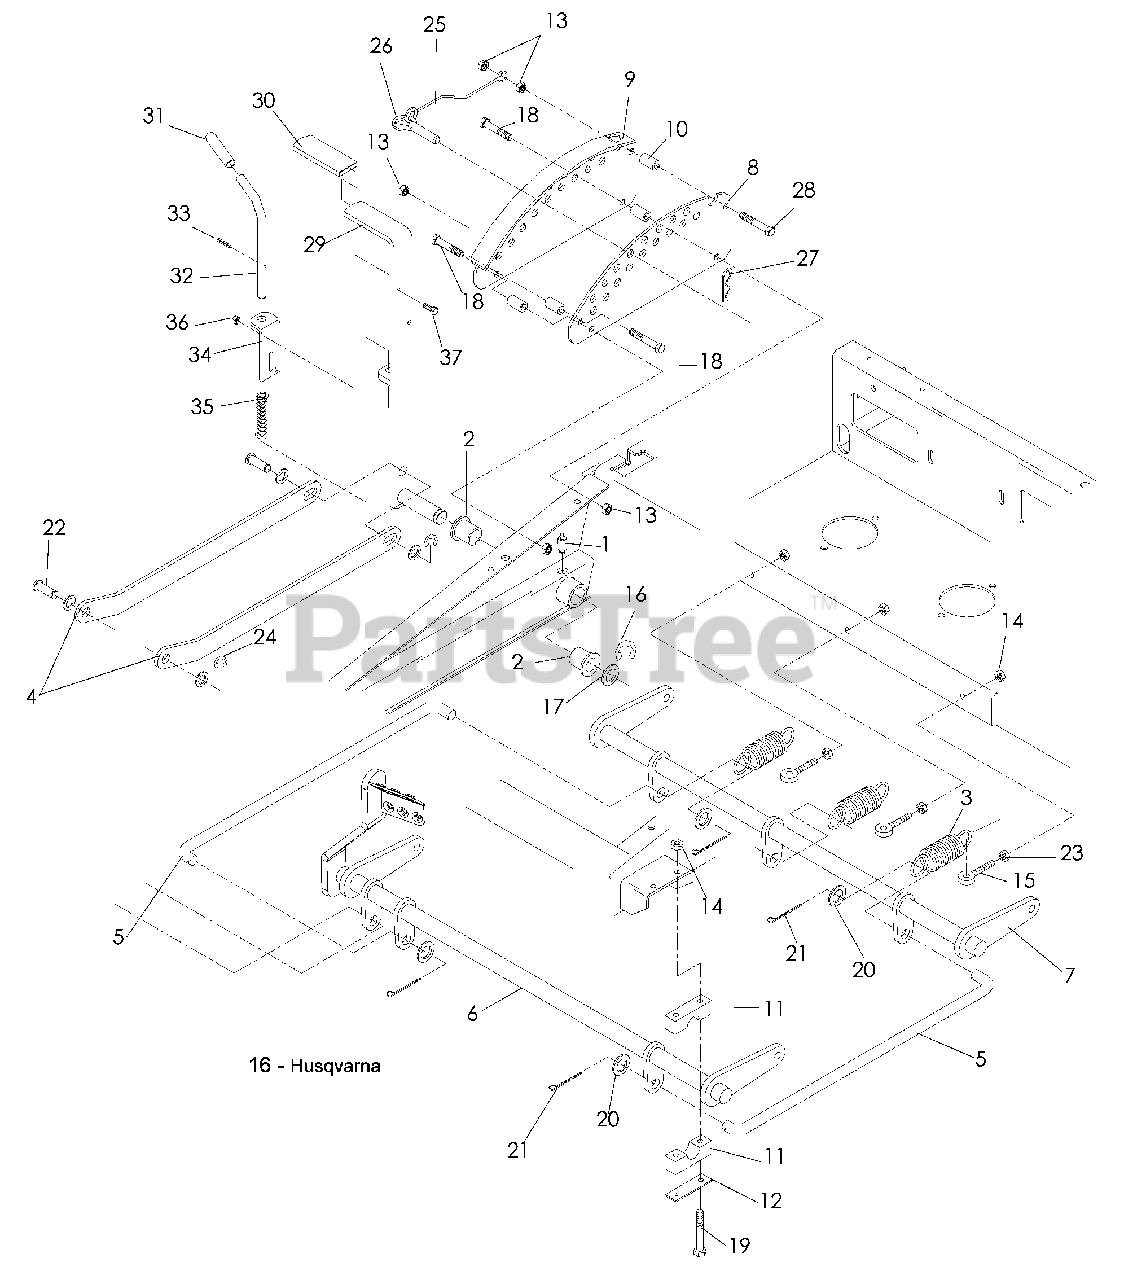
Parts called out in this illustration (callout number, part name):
1	ZERK, LONG
2	BUSHING, FLANGE
3	SPRING, DECK LIFT
4	LINKAGE, LIFT
5	LINK, CONNECTING
6	SHAFT ASSM W/PEDAL, FT
7	SHAFT, REAR LIFT
8	PLATE, ADJUSTMENT
9	PLATE, ADJUSTMENT
10	SPACER, DECK LIFT
11	BLOCKS, PILLOW
12	PLATE, SUPPORT
13	NUT 3/8-16 HEX NYLOC
14	NUT 5/16-18 HEX NYLOC
15	EYEBOLT 5/16 RH x 19/16
16	E-RING 7/8
17	BUSHING, MACHINE
18	HCS 3/8-16 x 2½
19	HCS 5/16-18 x 2¾
20	WASHER 5/8 SAE
21	PIN, COTTER 5/32 x 1¼
22	PIN, CLEVIS 5/8
23	NUT 5/16-18 WHIZ
24	E-RING 5/8
26	PIN, HITCH
28	HCS 3/8-16 x 2¾
29	LEVER, LIFT
30	CUSHION, HANDLE
31	GRIP, VINYL
32	PIN, LOCKING
33	PIN, GROOVED
34	PIN MOUNT, UPPER
35	SPRING, COMPRESSION
36	NUT ¼-20 CENTERLOCK
37	HCS ¼- 20 x ¾
